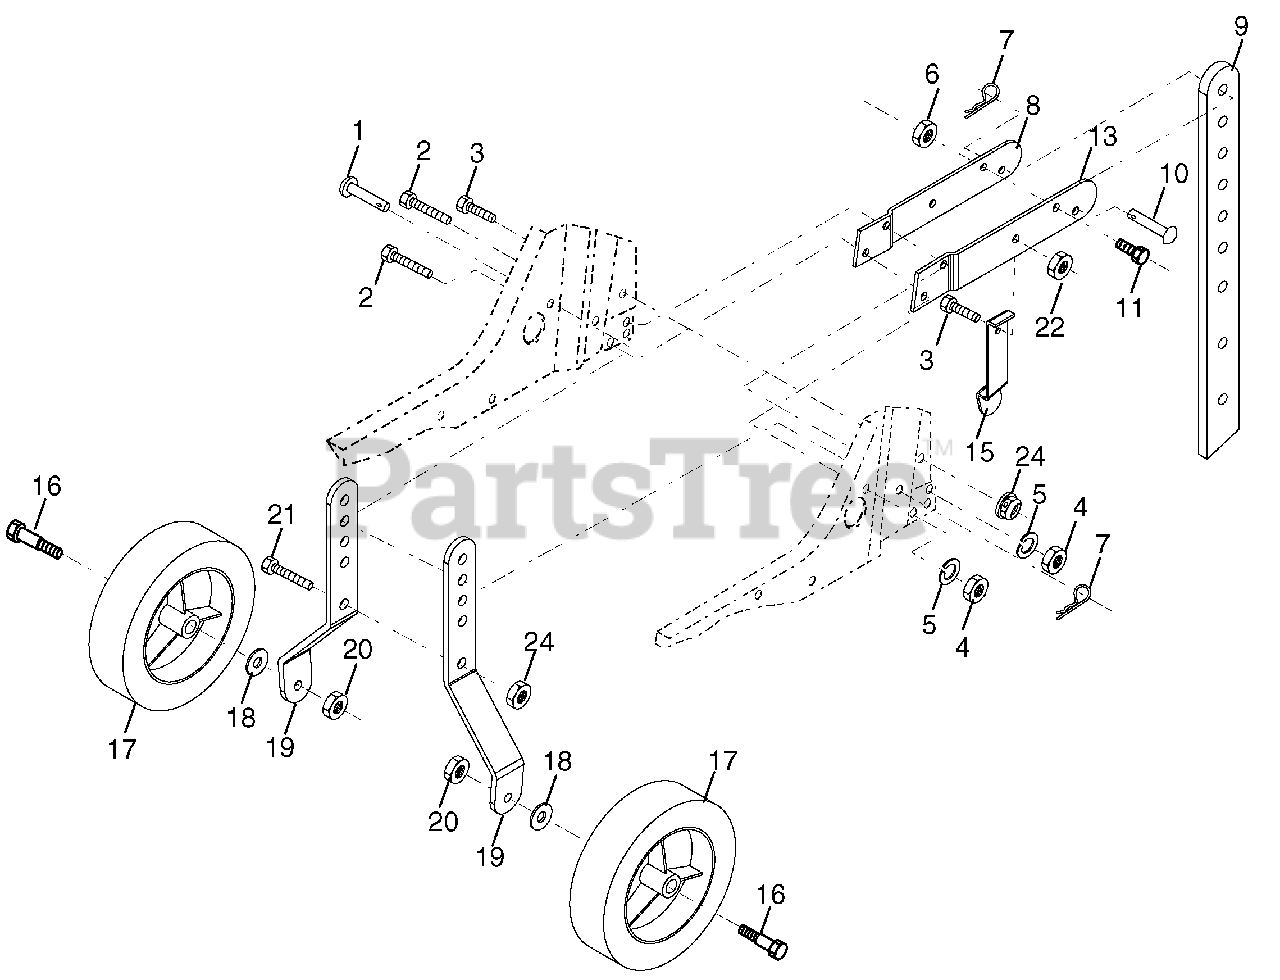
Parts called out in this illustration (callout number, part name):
1	Pin, Clevis
2	Bolt, Hex Head 5/16-18 x 1-1/4
3	Bolt, Hex Head 5/16-18 x 3/4
4	Nut, Hex 5/16-18
5	Washer, Lock 5/16
6	Locknut, Washer Insert 3/8-16
7	Clip, Hairpin
8	Support, Depth Stake, R.H.
9	Stake, Depth
10	Pin, Clevis
11	Bolt, Hex Head 3/8-16 x 1-3/4
13	Support, Depth Stake, L.H.
15	Spring, Stake
16	Bolt, Shoulder
18	Washer 13/32 x 13/16 x 11 Gauge
19	Bracket, Wheel
20	Nut, Hex, Crownlock 3/8-16
21	Bolt, Hex Head 5/16-18 x 1
22	Locknut, Washer Insert 5/16-18
24	Nut, Hex, Flangelock
